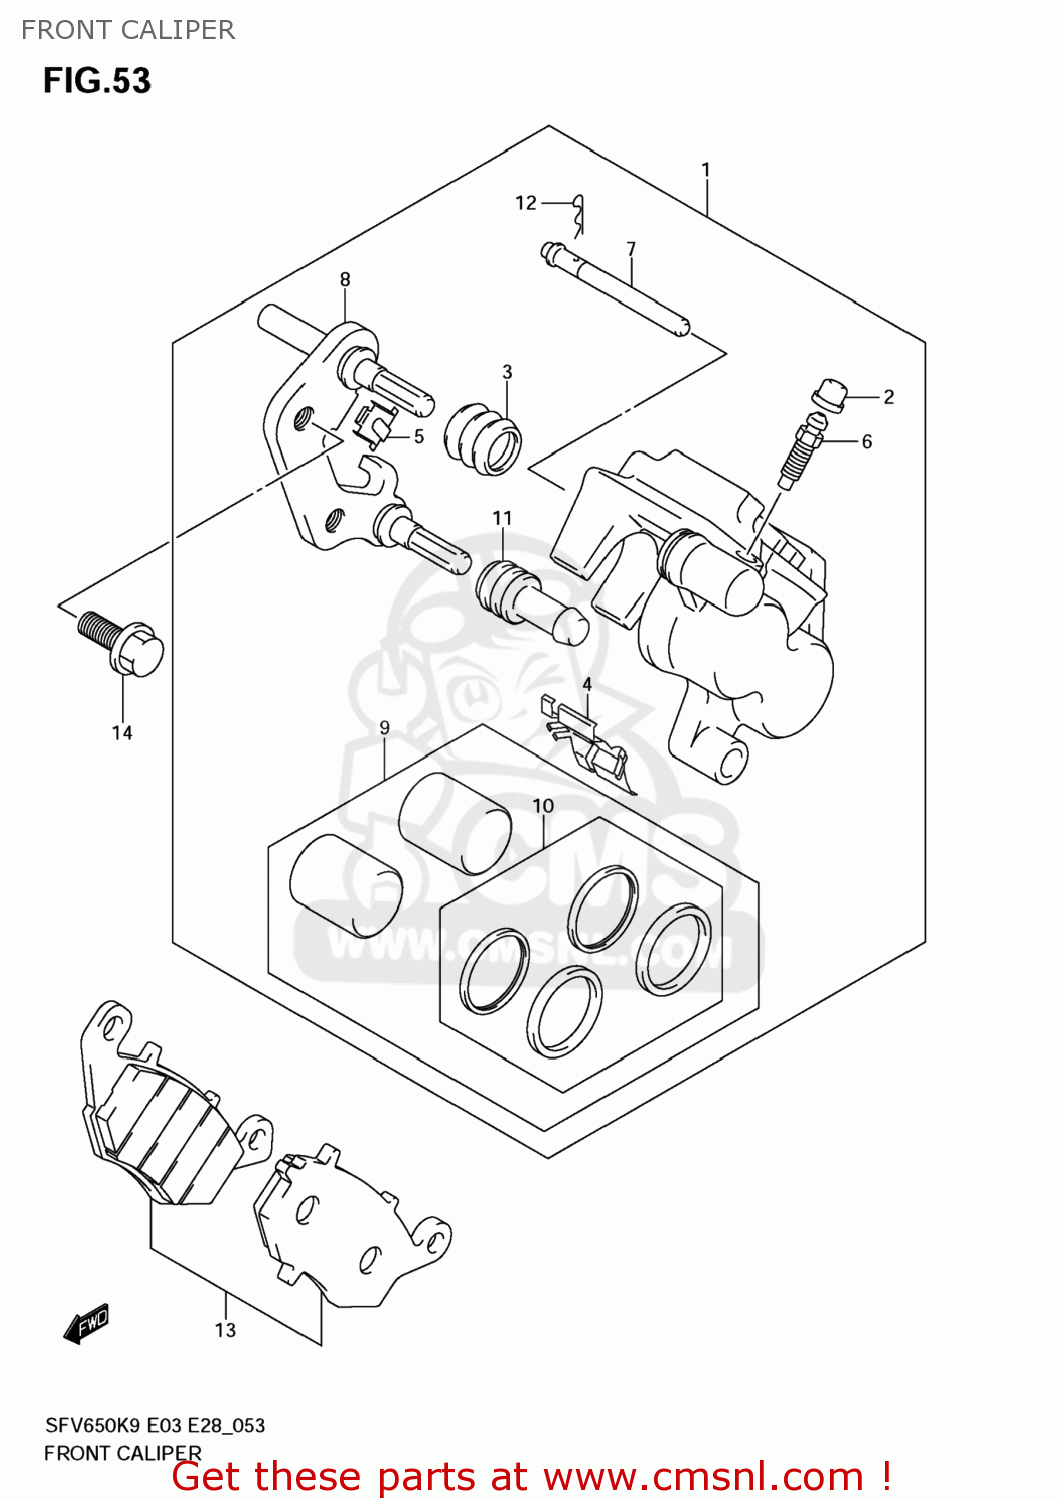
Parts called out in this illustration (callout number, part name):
1	CALIPER ASSY,FR,R
2	CAP,BLEEDER PLUG
3	BOOT,AXLE
4	SPRING,PAD,R
5	GUIDE,PAD
6	BLEEDER
7	PIN,PAD
8	CARRIER,CALIPER,R
9	PISTON SET
10	SEAL SET,PISTON
11	INSULATOR,AXLE
12	CLIP,PAD PIN
13	PAD SET (NAS)
14	BOLT
